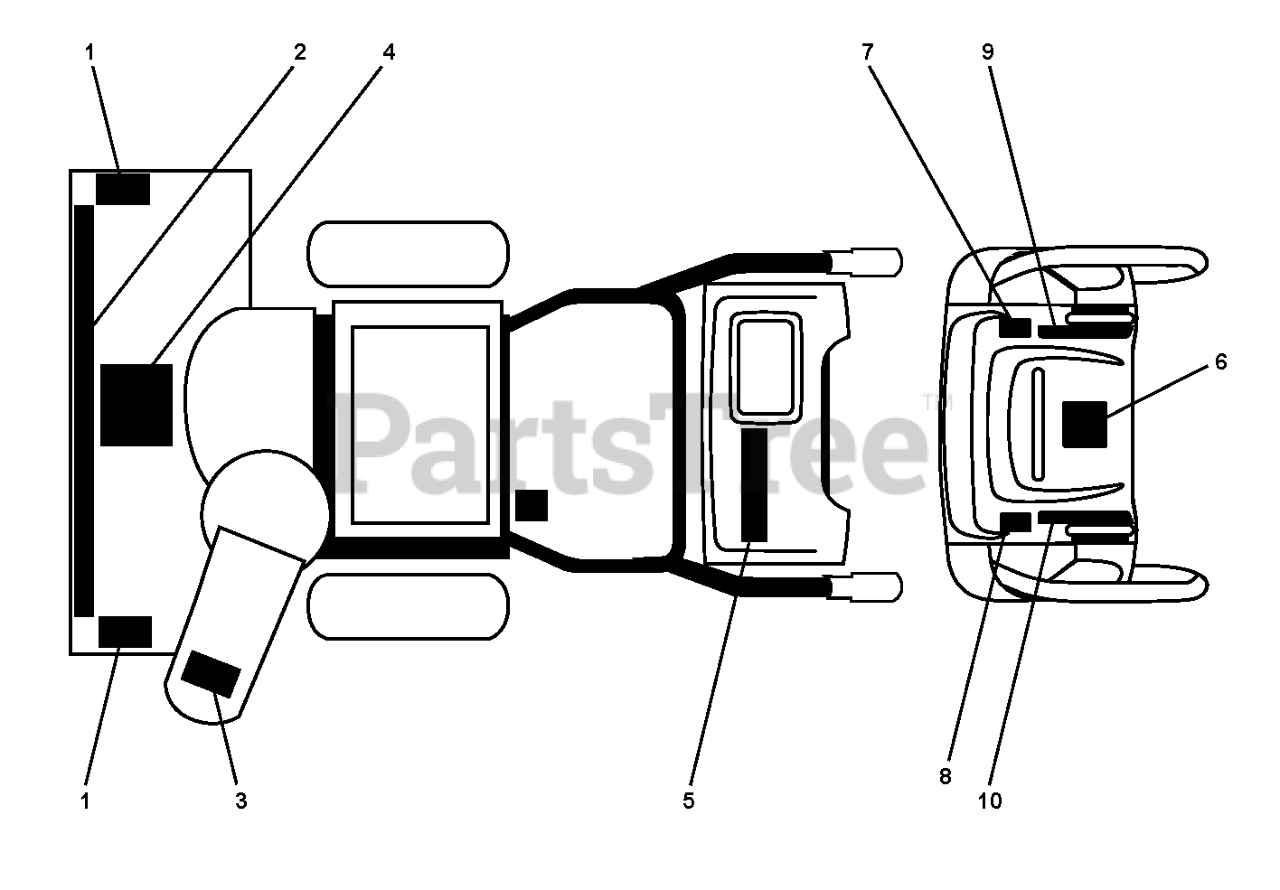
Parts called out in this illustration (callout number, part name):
1	DECAL.AUGER.SAFETY.
3	DECAL.CHUTE.SAFETY.
4	DECAL.AUGER."
6	DECAL.CONSOLE.INSTRUCTION
10	DECAL.REM.DEFLECTOR.LT
